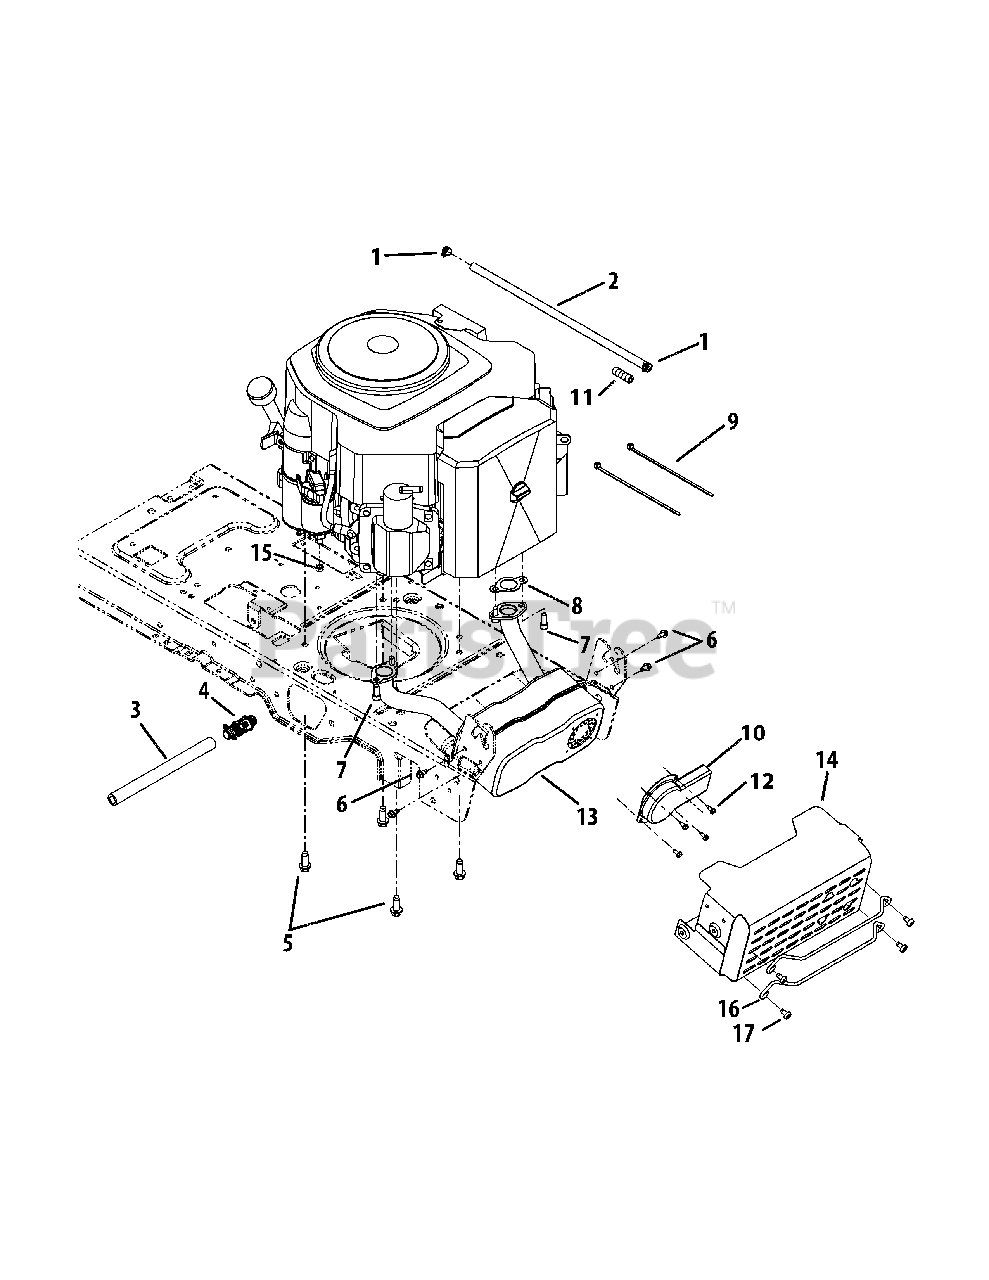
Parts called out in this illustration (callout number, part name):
1	Hose Clamp
2	Fuel Line 16" Lg.
3	Oil Drain Hose
4	Oil Drain
5	TT Screw 3/8-16 x 1.00
6	Hex Wash S-Tapp Scr 1/4-20 x .50
7	Scr. 5/16-18 x .75
8	Exhaust Gasket
9	Cable Tie
10	Long Muffler Deflector
11	Vent Hose (optional)
12	Hex AB Scr #8-18 x .50
13	Muffler
13	Muffler Guard Rod
14	Muffler Shield Assembly
15	Hex Sems Nut 1/4-20
18	TT Pan Hd Scr. 1/4-20 x .50
